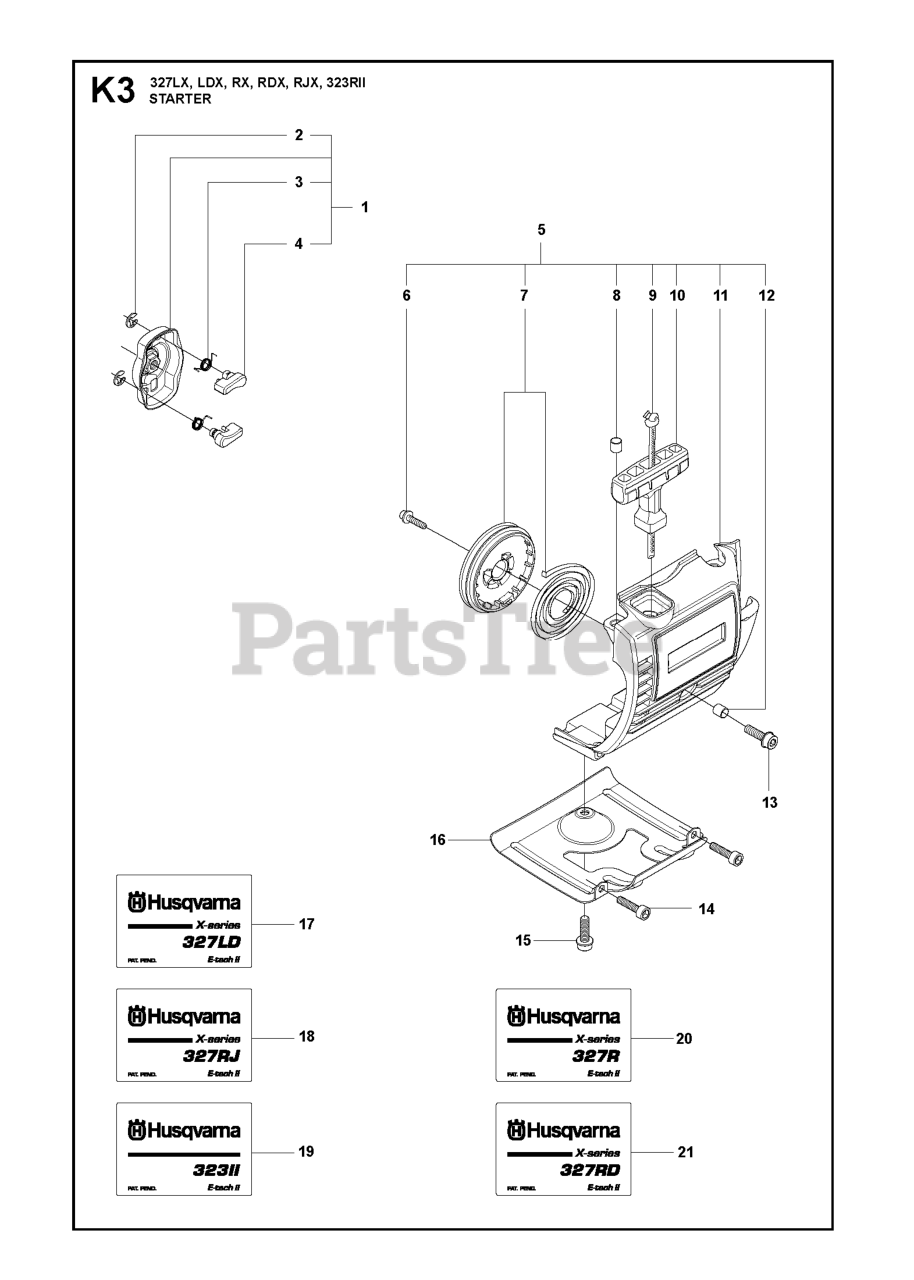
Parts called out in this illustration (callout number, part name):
1	STARTER PAWL BRIDGE
4	STARTER PAWL
5	STARTER ASSY
7	STARTER PULLEY ASSY.
8	SPACING SLEEVE
9	STARTER ROPE
10	STARTER HANDLE
11	RP STARTER HOUSING
12	SPACING SLEEVE
13	SCREW
15	SCREW
17	LABEL 327LDX
18	LABEL 327RJ
19	LABEL 323 RII
20	LABEL 327RX
21	LABEL 327RDX
